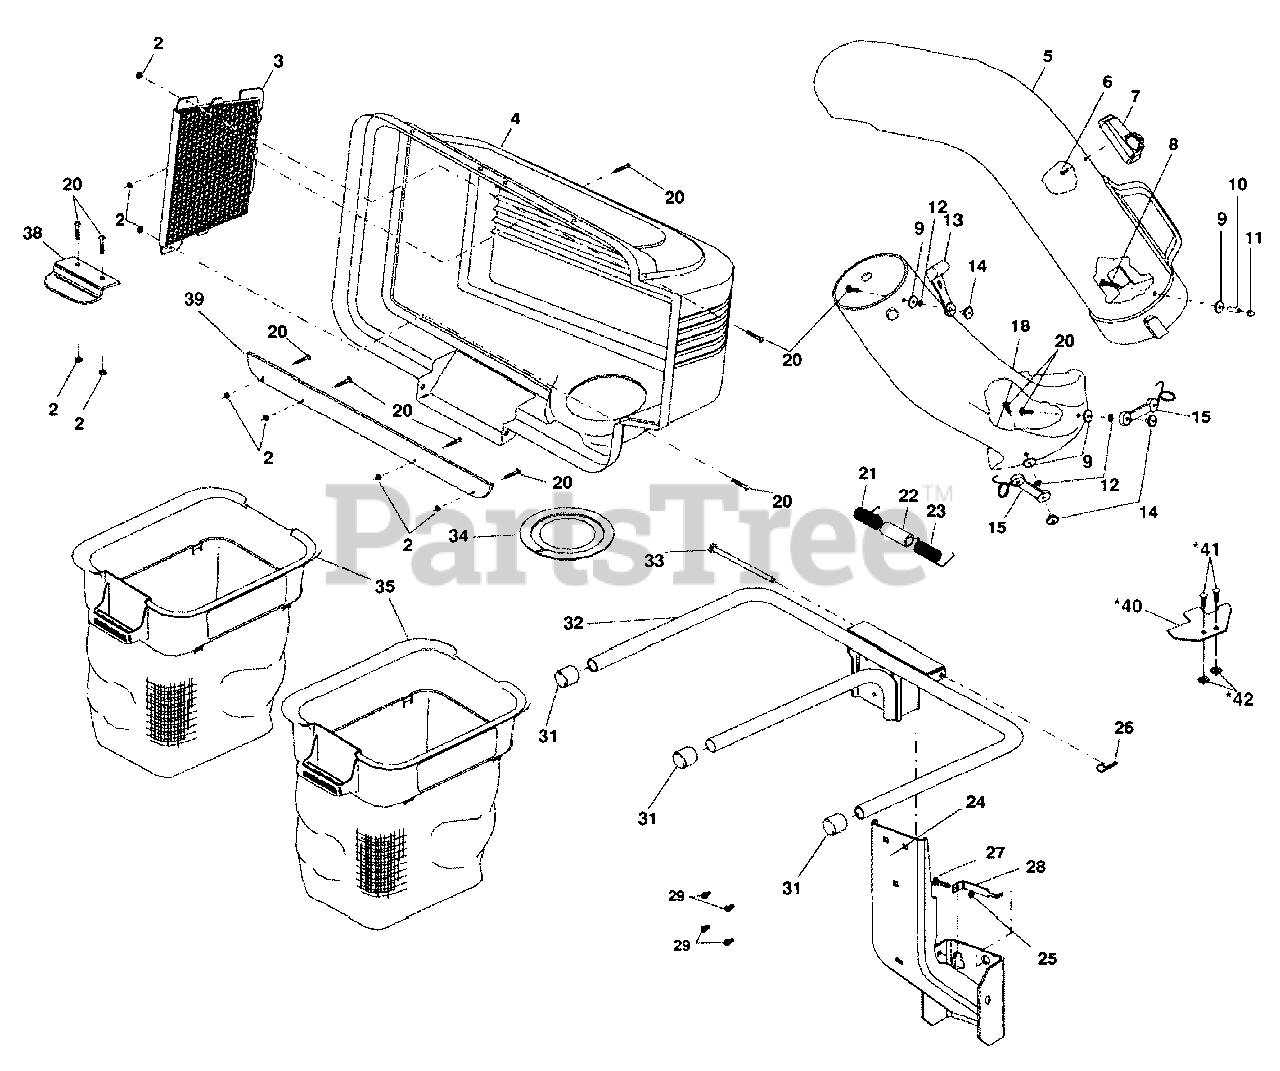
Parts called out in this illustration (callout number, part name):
2	NUT, CROWN LOCK #10-24
3	SCREEN, COVER
4	COVER ASSEMBLY
5	CHUTE, UPPER
6	SCREW, SPECIAL #10-14X1/2
7	FULL BAG INDICATOR
8	SCREW, #10-24 X 1-1/8
9	WASHER 3/16X3/4X16 GA.
10	SPACER, SPLIT
11	NUT, ACORN #10-24
12	WASHER, LOCK
13	LATCH, CHUTE
14	NUT, WELD
15	LATCH, HOOK
18	CHUTE, LOWER
20	SCREW #10-24 X 5/8
21	SPRING, COVER L.H., BLACK
22	SPACER, COVER
23	SPRING, COVER R.H., GRAY
24	SUPPORT ASSEMBLE
25	LOCKNUT
26	SPRING, RETAINER
28	BRACKET, LOCK
29	BOLT, SHOULDER 5/16-18
31	PLUG, TUBING END
32	BAGGER, FRAME
33	PIN, HINGE
34	GASKET, COVER
35	CONTAINER
38	LATCH HANDLE, COVER
39	STRIP, REINFORCEMENT
